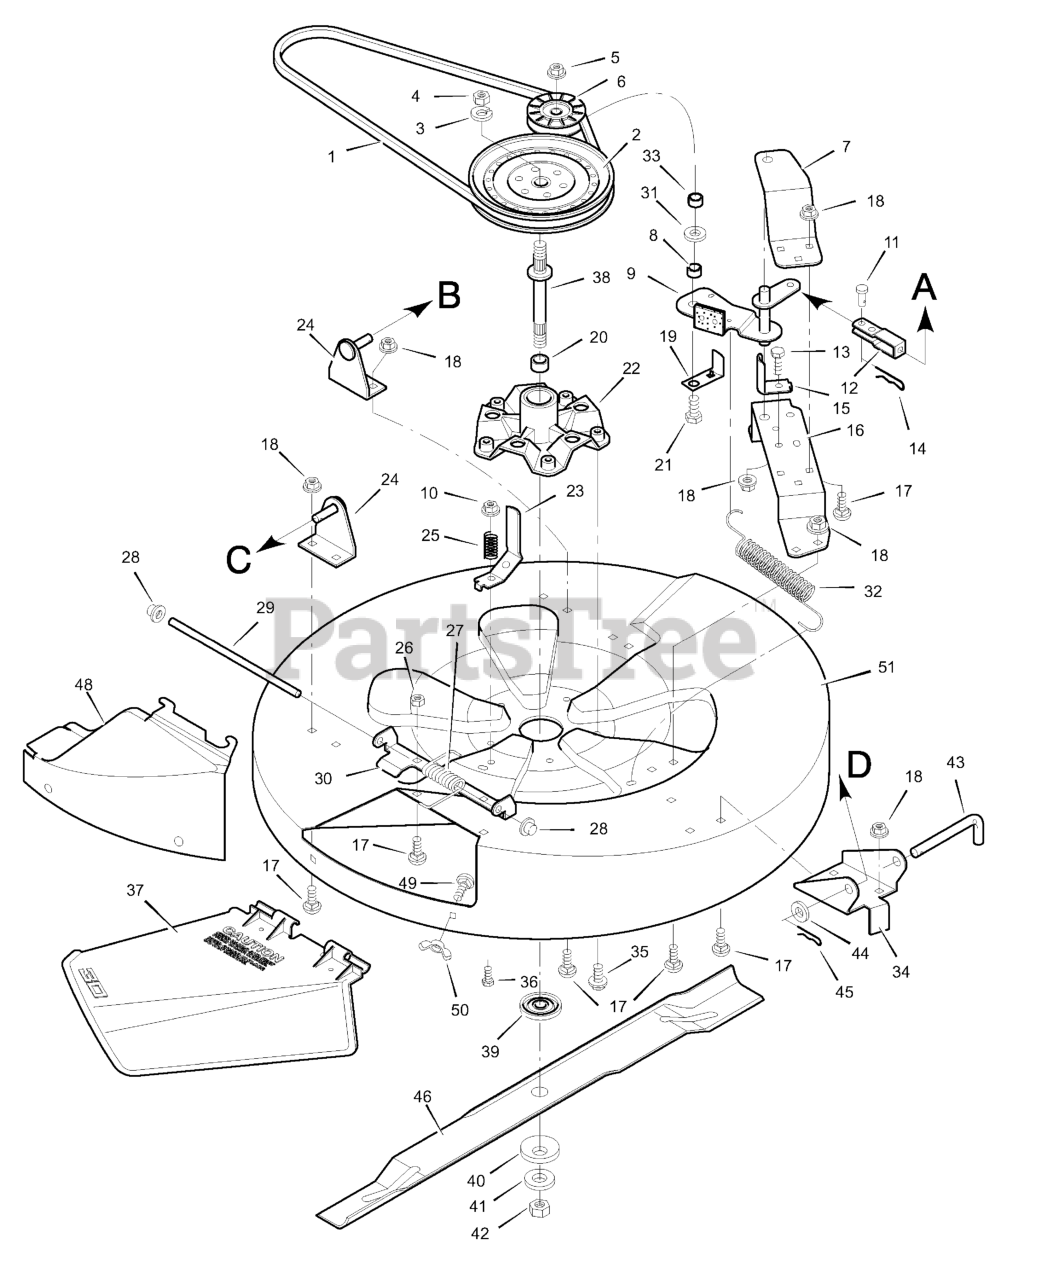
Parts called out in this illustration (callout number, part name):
1	Belt, Mower Drive
2	Pulley, Splined
3	Lockwasher
4	Locknut, Hex
5	Nut, Hex
6	Pulley, Idler
7	Bracket, Upper Idler
9	Assembly, Blade Idler
10	Locknut, Flange
11	Pin, Clevis
13	Bolt, Hex
14	Pin, Hair
15	Guide, Belt
16	Bracket, Lower Idler
17	Bolt, Carriage
18	Nut, Flange
19	Guide, Belt
21	Bolt, Hex
22	Housing, Mandrel
23	Guide, Belt
24	Bracket, Hanger
25	Spring, Compression
26	Nut, Hex
27	Spring - Torsional
28	Push On Cap
30	Hinge, Chute Deflector
32	Spring, Extension
34	Bracket, Front
36	Bolt, Hex
37	Deflector, Chute
38	Mandrel
39	Adapter, Blade
40	Washer, Belleville
41	Washer, Hardened
42	Nut, Hex
43	Pin, Pull
45	Pin, Hair
46	Blade, Mulching
48	Plate, Mulcher
49	Bolt, Carriage
50	Wingnut
